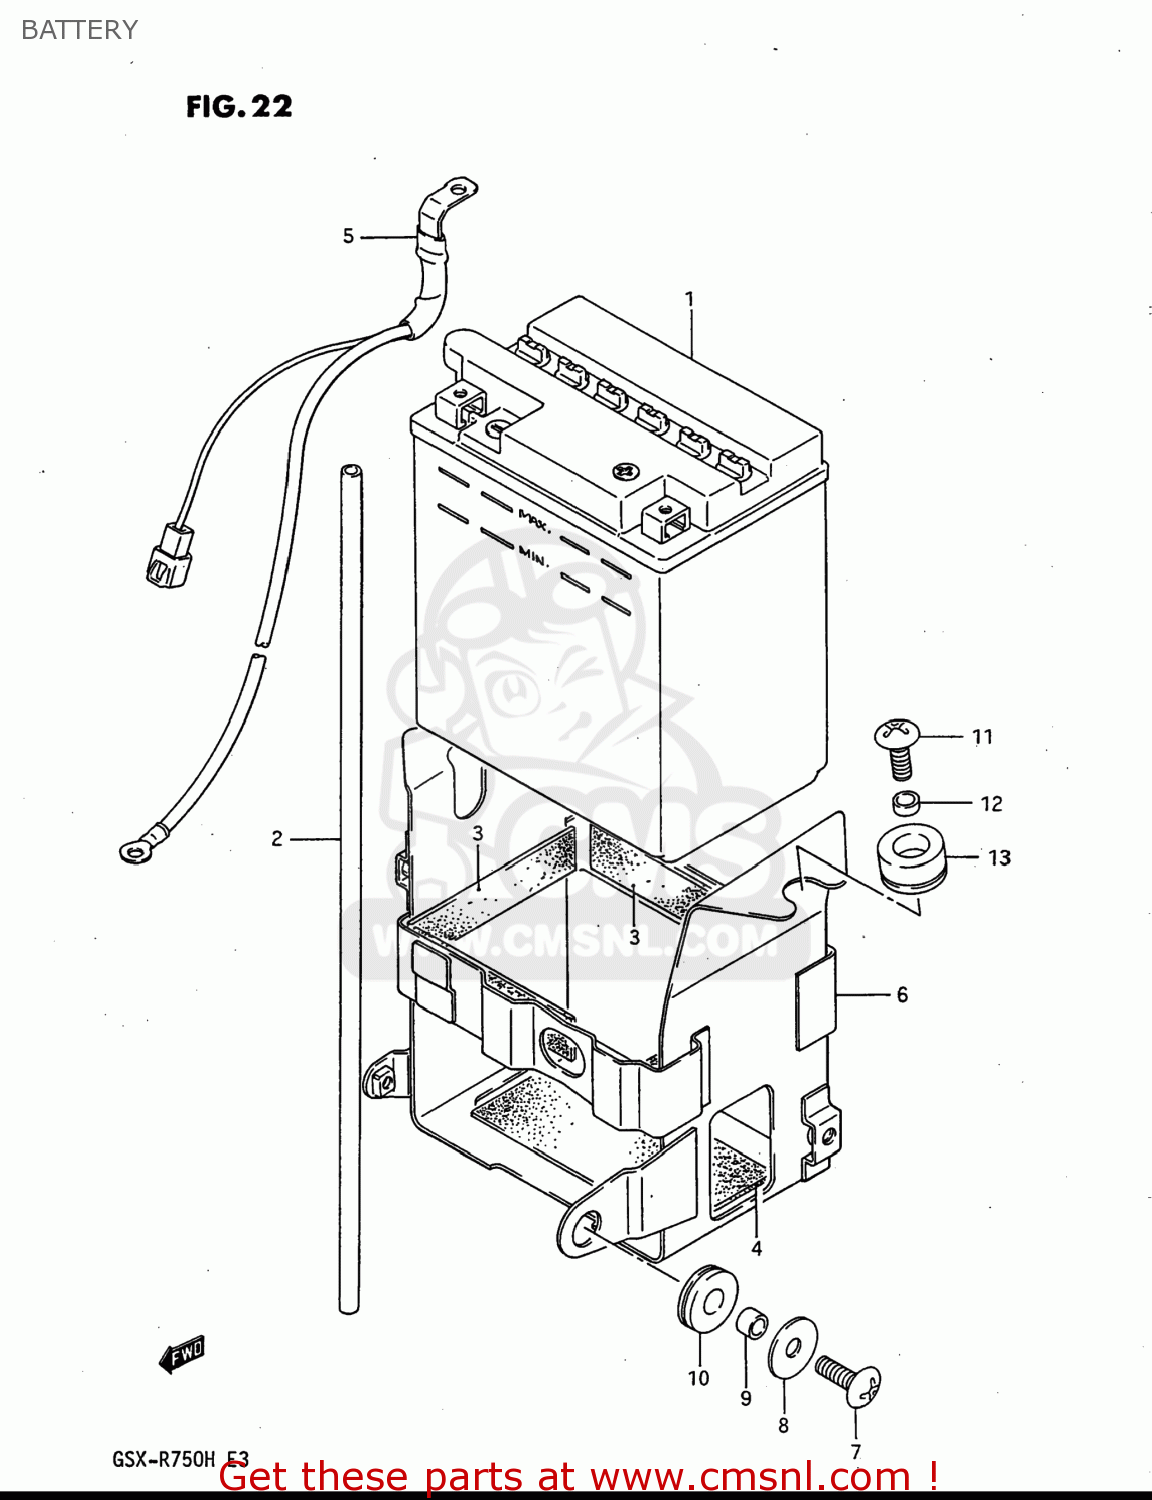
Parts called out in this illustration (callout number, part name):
1	BATTERY ASSY (12V)
2	HOSE,BATTERY EXHAUST
3	PROTECTOR,20X9
4	PROTECTOR(170X95X3.0)
5	WIRE,BATTERY MINUS LEAD
6	HOLDER,BATTERY
7	SCREW
8	WASHER
9	SPACER
10	CUSHION
11	SCREW
12	SPACER
13	CUSHION,HOLDER BATTERY UPR
